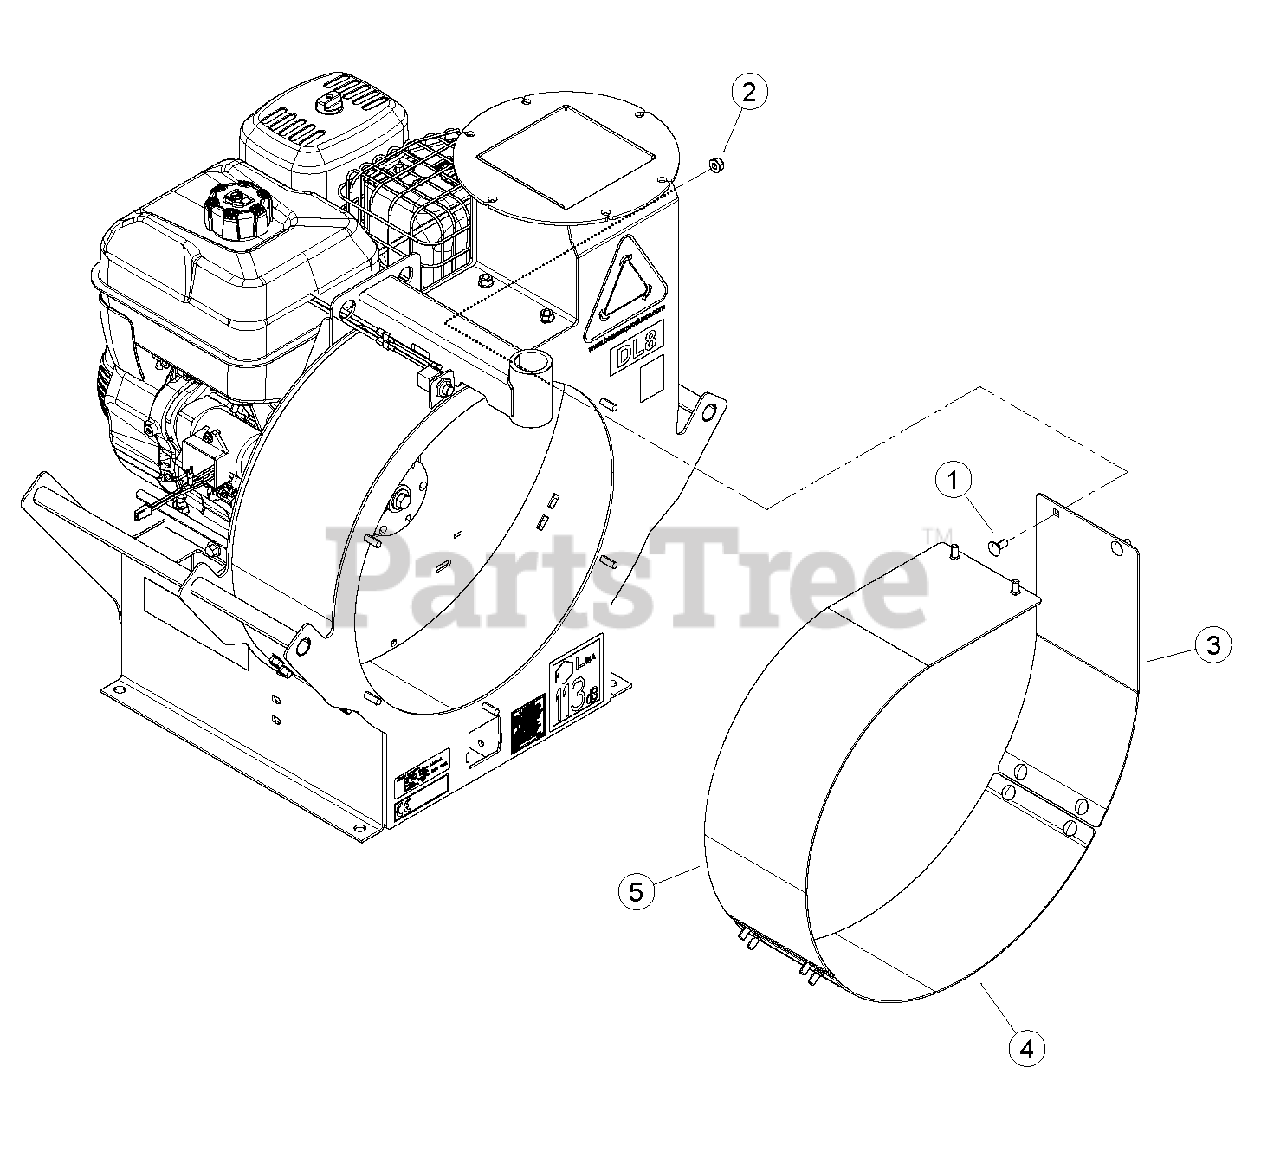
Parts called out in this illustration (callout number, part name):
1	BOLT, 5/16X3/4 GR5 NC ZP CRG
2	NUT, 5/16-18 NYLOCK FLANGE
3	LINER, WEAR RIGHT
4	LINER, WEAR MIDDLE
5	LINER, WEAR LEFT
